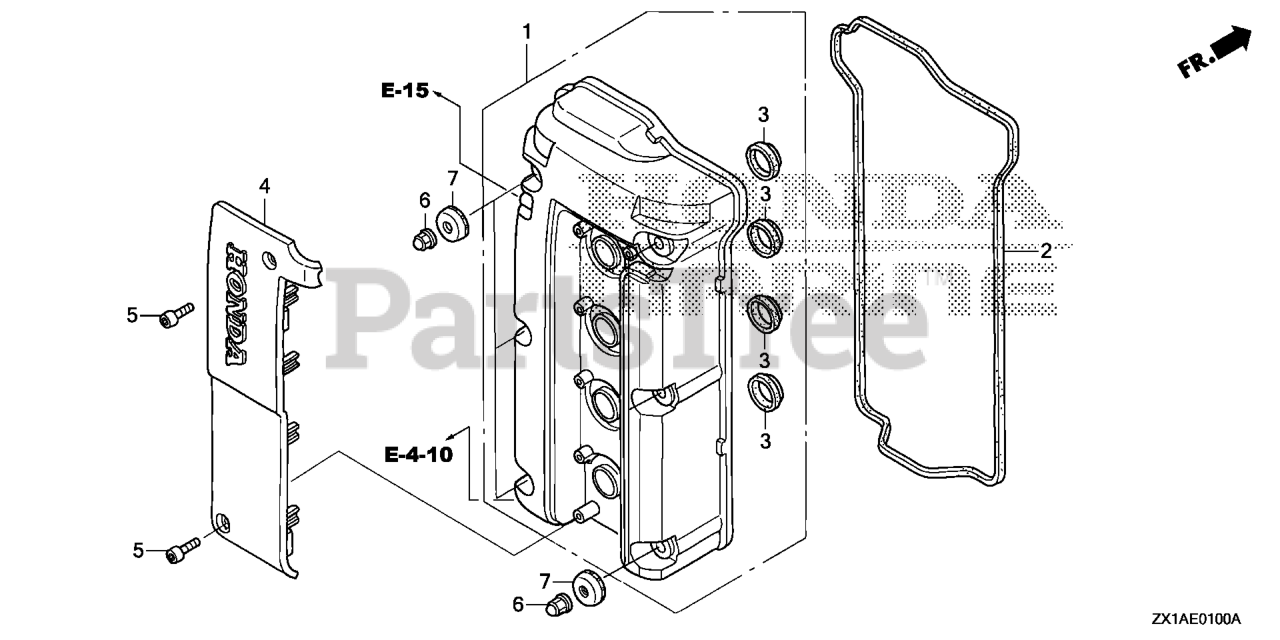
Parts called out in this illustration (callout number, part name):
1	COVER, CYLINDER HEAD *NH8* (DARK GRAY) (FOR 14540-RWC-A02)
2	GASKET, CYLINDER HEAD COVER
3	SEAL, SPARK PLUG TUBE (NOK)
4	COVER, PLUG HOLE COIL
5	BOLT, SOCKET (6X25)
6	NUT, FLANGE CAP (6MM)
7	WASHER, HEAD COVER
